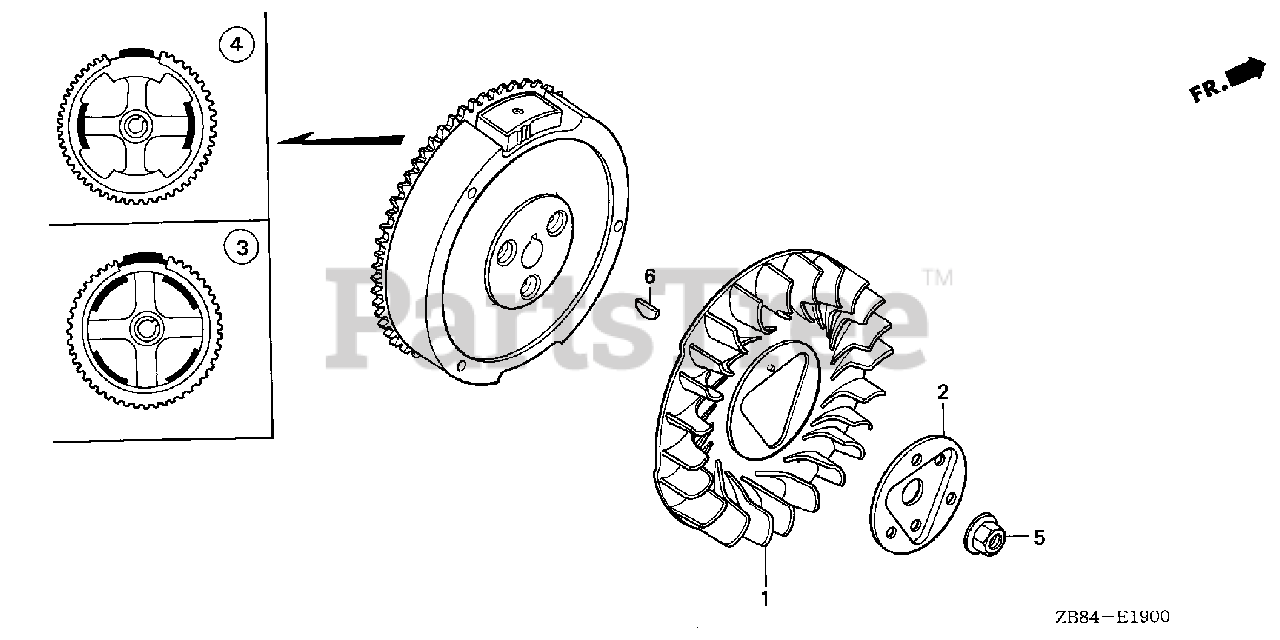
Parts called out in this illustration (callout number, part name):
1	FAN, COOLING
2	PLATE, COOLING FAN SETTING
4	FLYWHEEL (SEL-LAMP)
5	NUT, SPECIAL (16MM)
6	KEY, SPECIAL WOODRUFF (25X18)
